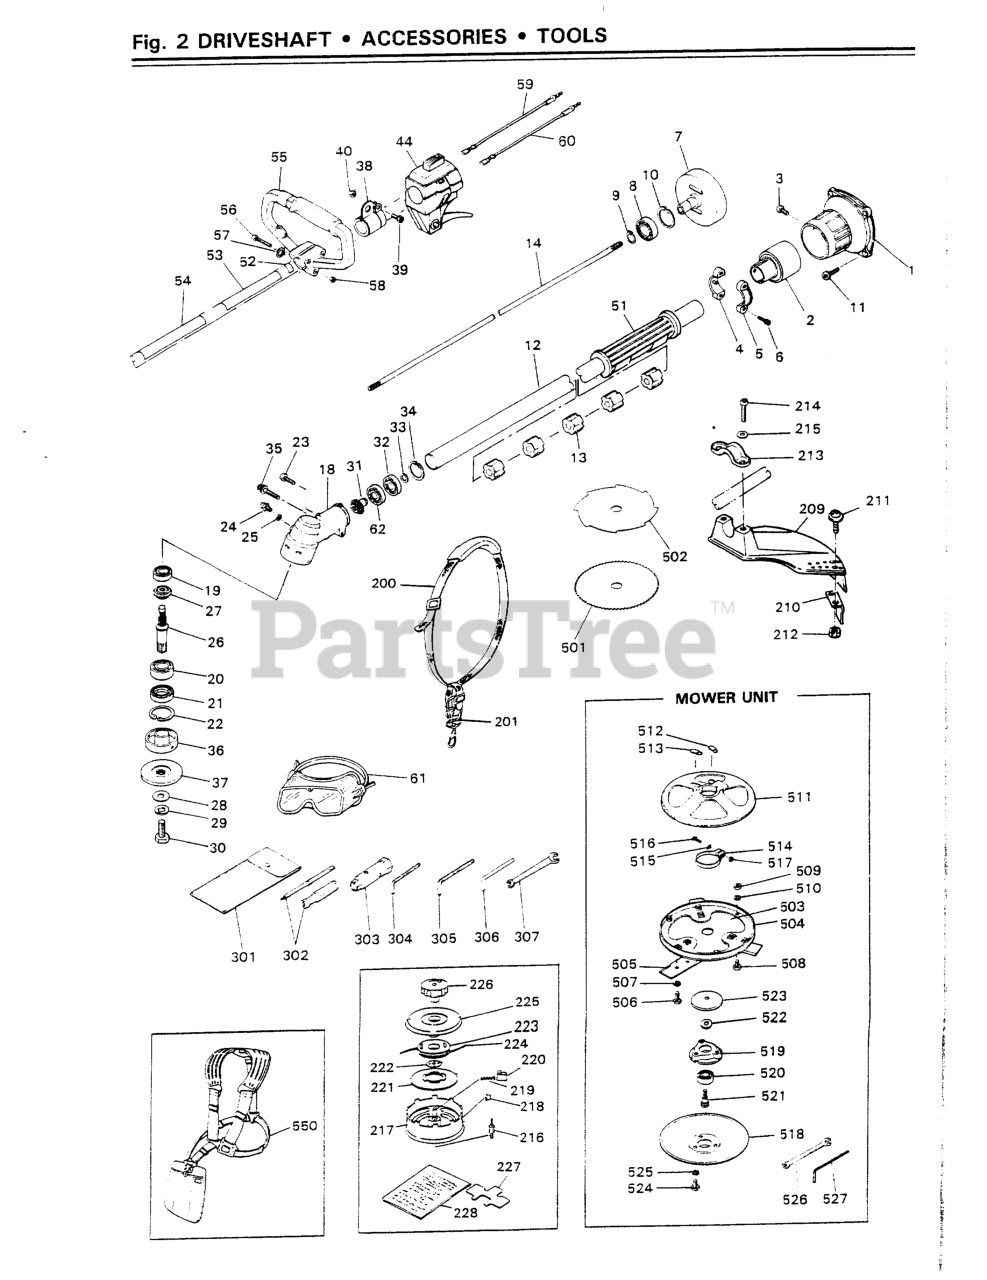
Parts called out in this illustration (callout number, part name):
3	SCREW, M6 x 10
6	BOLT
7	DRUM, CLUTCH
8	BEARING
9	RING, SNAP, M15 X 1.0
10	RING, SNAP, M35 X 1.5
14	SHAFT, SPLINE
19	BEARING (RPLS T3403-13510)
21	SEAL, OIL
22	RING, SNAP, M32 x 1.2
23	BOLT, M5 X 10
24	FITTING, GREASE
25	WASHER, M6 X .8
27	GEAR, BEVEL
28	WASHER, M8 x 2.3 (RPLS -20823)
29	WASHER (RPLS 3180-13270)
30	BOLT, LH
33	RING, SNAP
35	BOLT, M6 x 1.35
36	HOLDER (A)
37	HOLDER (B)
38	HANGER COMP (USE 9366-17100)
39	BOLT, M6 x 16
40	NUT, M6 X 5
52	LABEL, POSITIONING
53	PLATE, NAME
55	HANDLE ASSEMBLY
56	SCREW, M5 x 30(RPLS 0263-00530
57	WASHER, M5 x 10
58	NUT, M5 X 4
59	CORD-A, BLACK
60	CORD-B, RED
62	BEARING (RPLS T3403-13510)
210	BLADE
211	SCREW, M5 x 12
212	NUT
213	CLAMP
214	BOLT, M6 x 1.30
215	WASHER, M6 X 15
216	ADAPTER-MALE
217	HOUSING, SPOOL
218	EYELET (RPLS -15220)
219	SPRING, RED
220	SLIDE CAM (1 PC)
221	CAM DISK
222	NUT, FLAT
227	FASTENING TOOL
302	SCREWDRIVER
304	WRENCH (TOOL)
305	WRENCH (TOOL)
306	BAR
307	SPANNER, 8 X 10 (RPLS 2540- )
501	BLADE, CIRCULAR SAW
502	BLADE, EDDY SAW
506	BOLT, BLADE MTG.
507	WASHER, M8 x 20
508	BOLT, M6 x 10
509	NUT, M6 X 5
510	WASHER, M6 X 15
516	BOLT, M5 X 16
517	NUT, M5 X 4
518	STABLIZER
519	BEARING CASE
525	WASHER, M6 X 15
